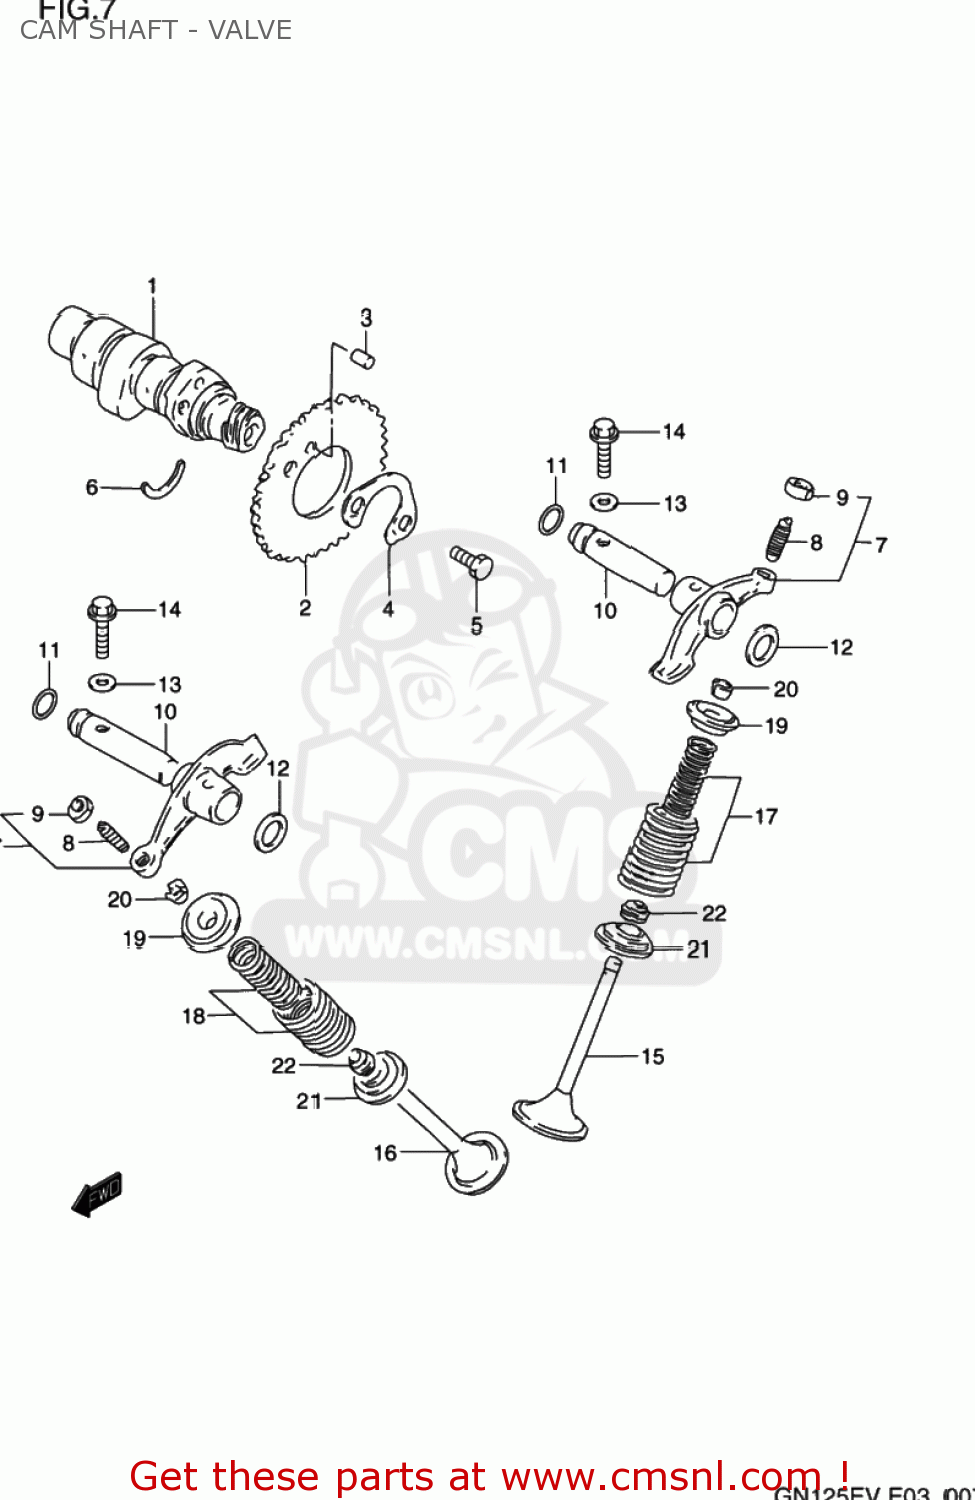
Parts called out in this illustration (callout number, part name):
1	CAMSHAFT
2	SPROCKET,CAMSHAFT
3	PIN(5X8)
4	WASHER,SPROCKET
5	BOLT(6X10.5)
6	C RING
7	ARM ASSY,VALVE ROCKER
8	SCREW,TAPPET ADJUSTING
9	NUT,ADJUSTING SCREW
10	SHAFT,VALVE ROCKET
11	O RING(D:1.9,ID:8.6)
12	WASHER
13	GASKET(5.8X13X1.2) (NAS)
14	BOLT
15	VALVE,INTAKE
16	VALVE,EXHAUST
17	SPRING SET,VALVE
18	SPRING SET,VALVE
19	RETAINER,VALVE SPRING
20	COTTER,VALVE
21	SEAT,VALVE SPRING
22	SEAL,OIL(5.5X11X8.2)
